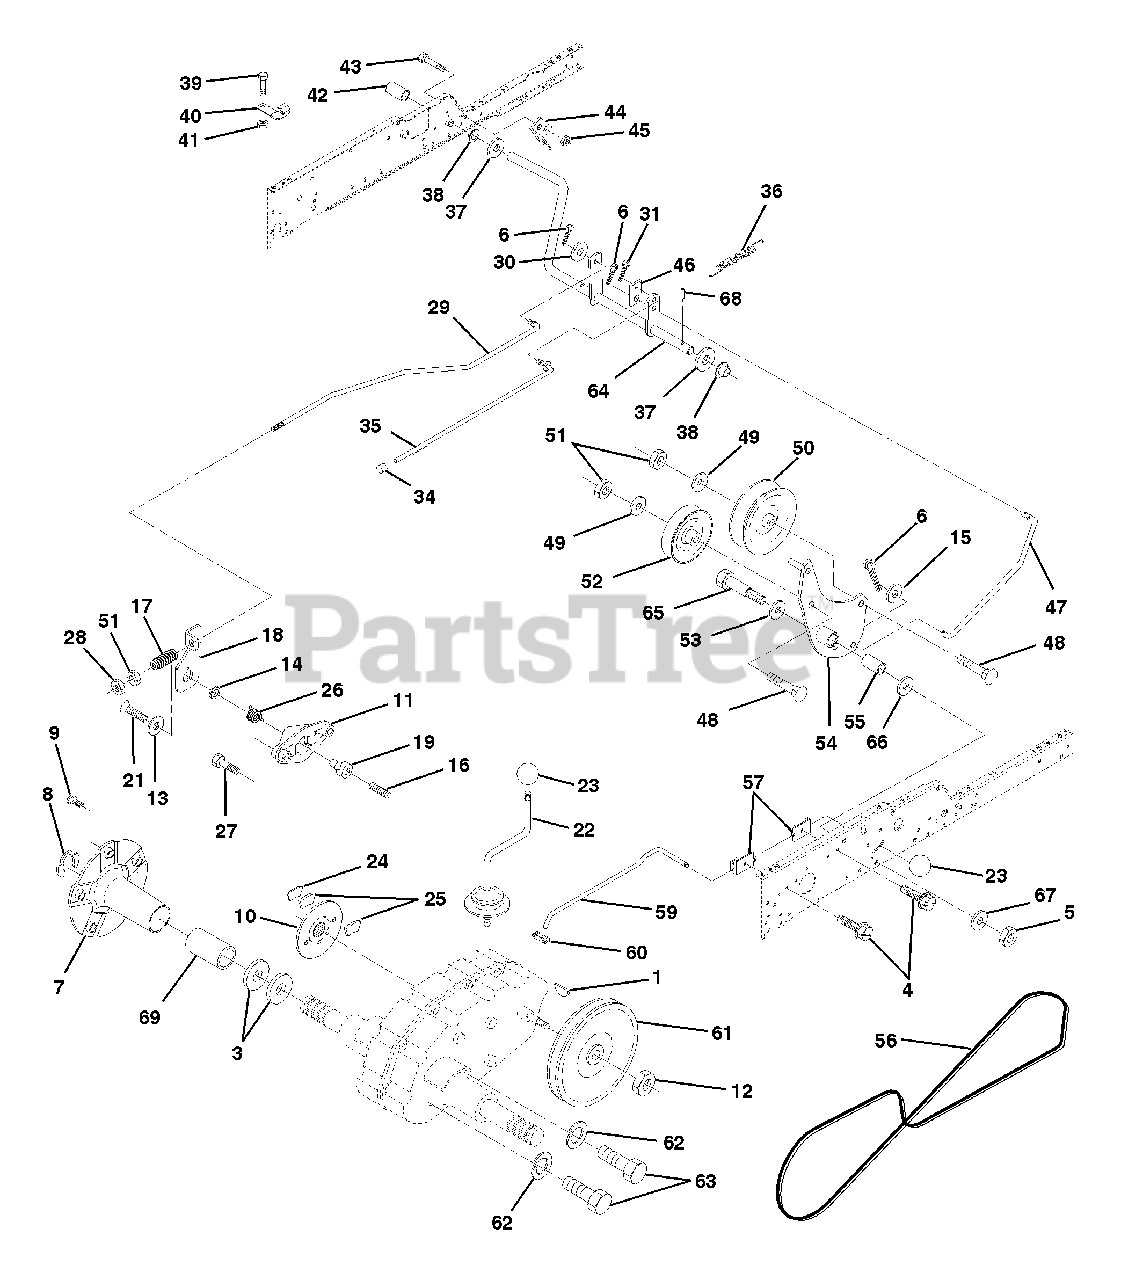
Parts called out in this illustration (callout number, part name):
1	Key Woodruff
3	Washer Thrust Axle Harden
4	Screw Thdrol 5/16-18 x 1/2 TYT
5	Nut Crownlock 3/8-16
6	Pin Cotter 1/8 x 3/4
7	Wheel Hub Asm.
10	Disc Brake
11	Yoke Brake Disc
12	Locknut 1/2-20
13	Washer Special
15	Washer 13/32 x 13/16 x 16 Ga
16	Set Screw 1/4-28 x 3/4
18	Lever Brake
19	Cam Brake Disc
21	Screw Flat Head 1/4-28 x 3/4
22	Gearshift Lever Assembly
24	Support Puck Brake
25	Puck Brake Top
26	Spring Return
27	Screw Hex Wsh Thd 5/16-18 x 1-3/4
28	Nut Hex Jam 3/8-16
30	Washer 13/32 x 1 x 14 Ga
31	Pin Cotter 3/32 x 3/4
34	Cap Plunger
35	Rod Parking Brake
36	Spring Extension
37	Washer 25/32 x 1-1/4 x 16 Ga
39	Screw Fin #10-24 x 1
40	Actuator Interlock Switch
41	Nut Lock #10-24
42	Cover Pedal
43	Bolt Hex Head 1/4-20 x 3/4
44	Bracket interlock
45	Nut Lock W/Insert 1/4-20
46	Retainer Spring
47	Clutch Rod
48	Bolt Carriage 3/8-16 x 1-3/4 Gr 5
49	Washer 13/32 x 7/8 x 13 Ga
50	Pulley Idler Flat
51	Nut Lock Hex 3/8-16
52	Pulley Idler Grooved
53	Washer Hardened
54	Clutch Arm Asm
55	Bearing, Idler
57	Bracket Shift Rod Hi-Lo
59	Shift Rod Hi-Lo
60	Spring Clip Connecting Link
61	Pulley Transaxle
62	Washer Lock 7/16
63	Bolt Fin Hex 7/16-14 x 1-1/4
64	Shaft Clutch/Brake Pedal
65	Bolt Shoulder
66	Washer Hardened
67	Washer 13/32 x 13/16 x 12 Ga.
